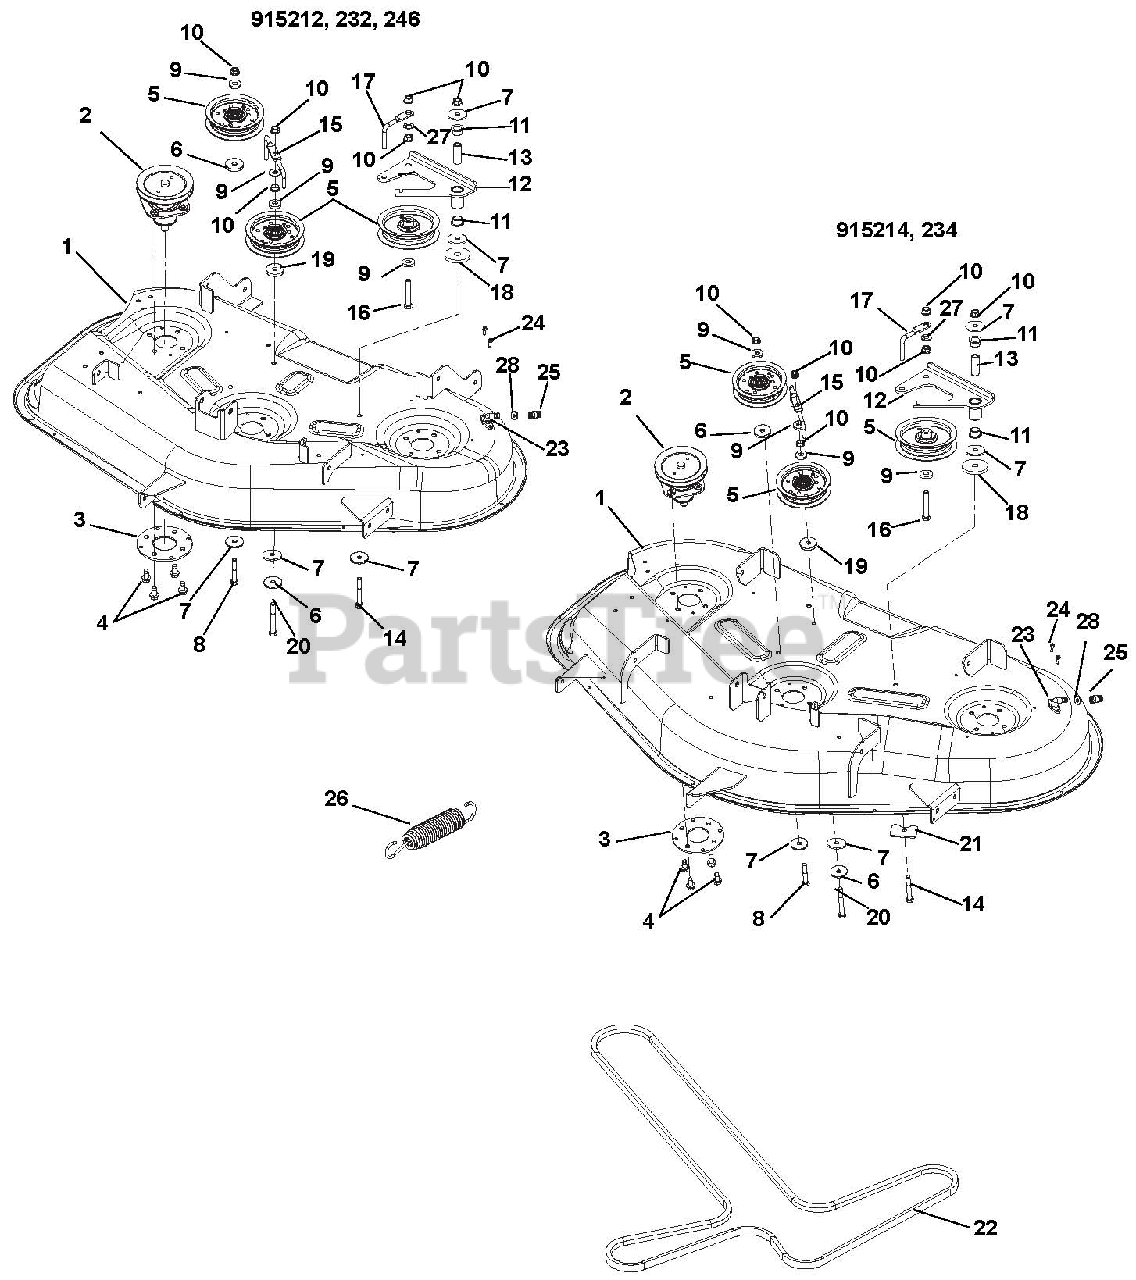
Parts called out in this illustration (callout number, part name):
1	KIT,42" GRAVELY COMPLETE DECK
1	KIT, 42" GRAVELY DECK W/DECALS
1	KIT,GRAVELY 50" COMPLETE DECK
1	KIT, 50" GRAVELY DECK W/DECALS
2	KIT, DECK SPINDLE ASM (42)
2	KIT, DECK SPINDLE ASM (34/50)
3	PLATE-REINF, SPINDLE
4	@SCR-TAP .38-16X.75 HWH TR YWZ
5	ASM, IDLER 4"
6	WSHR,FLT STL.406X1.50X.245YWZC
7	WSHR-FL-STL .380X1.50X.125YWZC
8	@BLT-HEX .38-16X2.25 GR5 YWZC
9	WSHR-FL-STL .406X1.00X.188 YWZ
10	@NUT-LK-TOP-FLG .38-16 YWZC
11	BSHG-FLG, .625X.750X.500X1.00
12	IDLER ARM
13	SPACER, .375IDX.625ODX1.66 PM
14	@BLT-HEX .38-16X3.00 GR5 YWZC
15	WIREFORM, BELT FINGER
16	@BLT-HEX .38-16X2.25 GR5 YWZC
17	WIREFORM, BELT FINGER
18	WSHR-FL-STL .469X2.00X.25 YWZC
19	@WSHR-FL-STL.438X1.00X.083 YWZ
20	@BLT-HEX .38-16X2.75 GR5 YWZC
21	PLATE-DECK REINF.
22	V-BELT, 4L-WRAPPED
23	ASSY, WASHOUT PORT W/ O-RING
24	@SCR-TAP .25-20X.62 HWH TR YWZ
25	COUPLING, QUICK DISCONNECT
26	SG-TENS .135X.98X6.0 WLD 62
27	@WSHR-FL-STL.406X.812X.065 YWZ
28	O-RING .362X.103X.568
